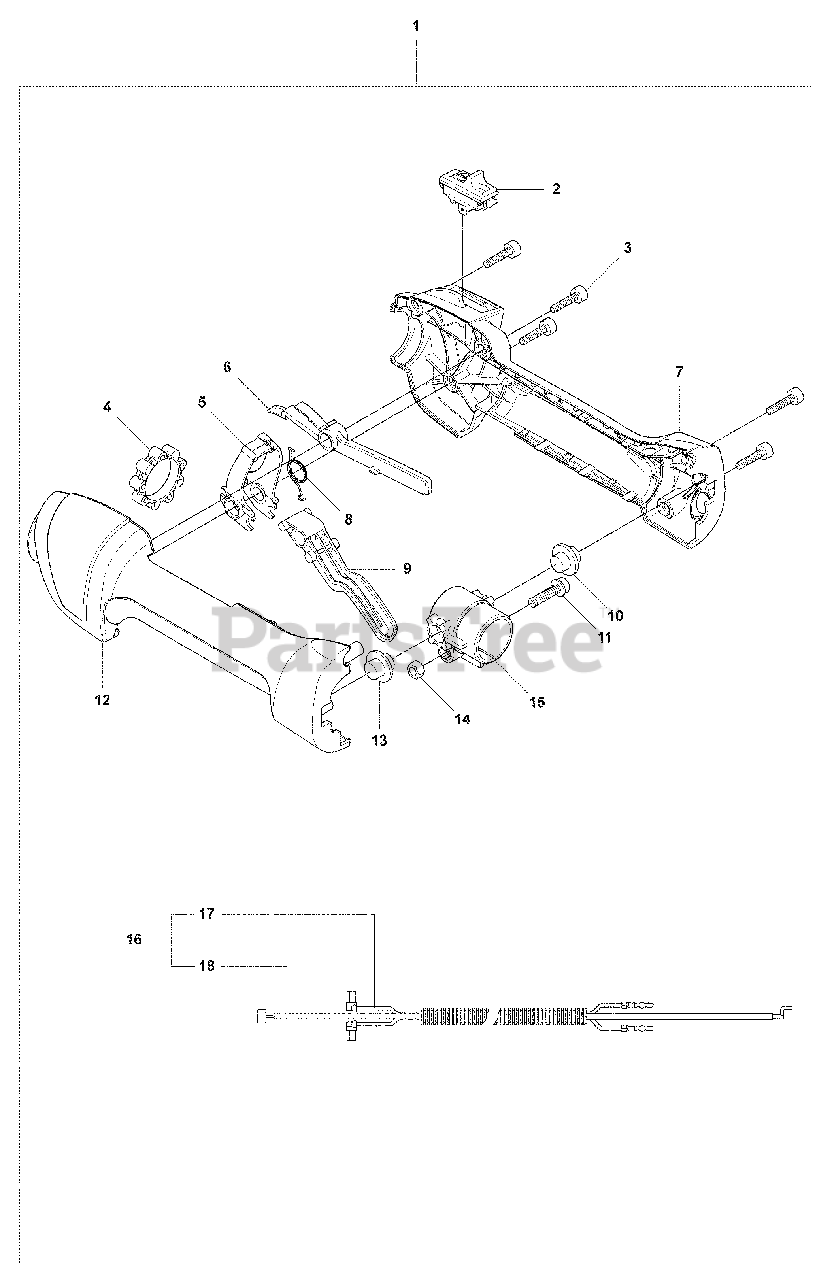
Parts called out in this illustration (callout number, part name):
2	Stop Button
4	Vibration Damper
6	Throttle Lock
8	Return Spring
9	Throttle Trigger
10	Vibration Absorber
13	Vibration Absorber
14	Hex Nut, M5 X .80 DIN
17	Short-Circuit Cable
18	Throttle Wire Assembly
